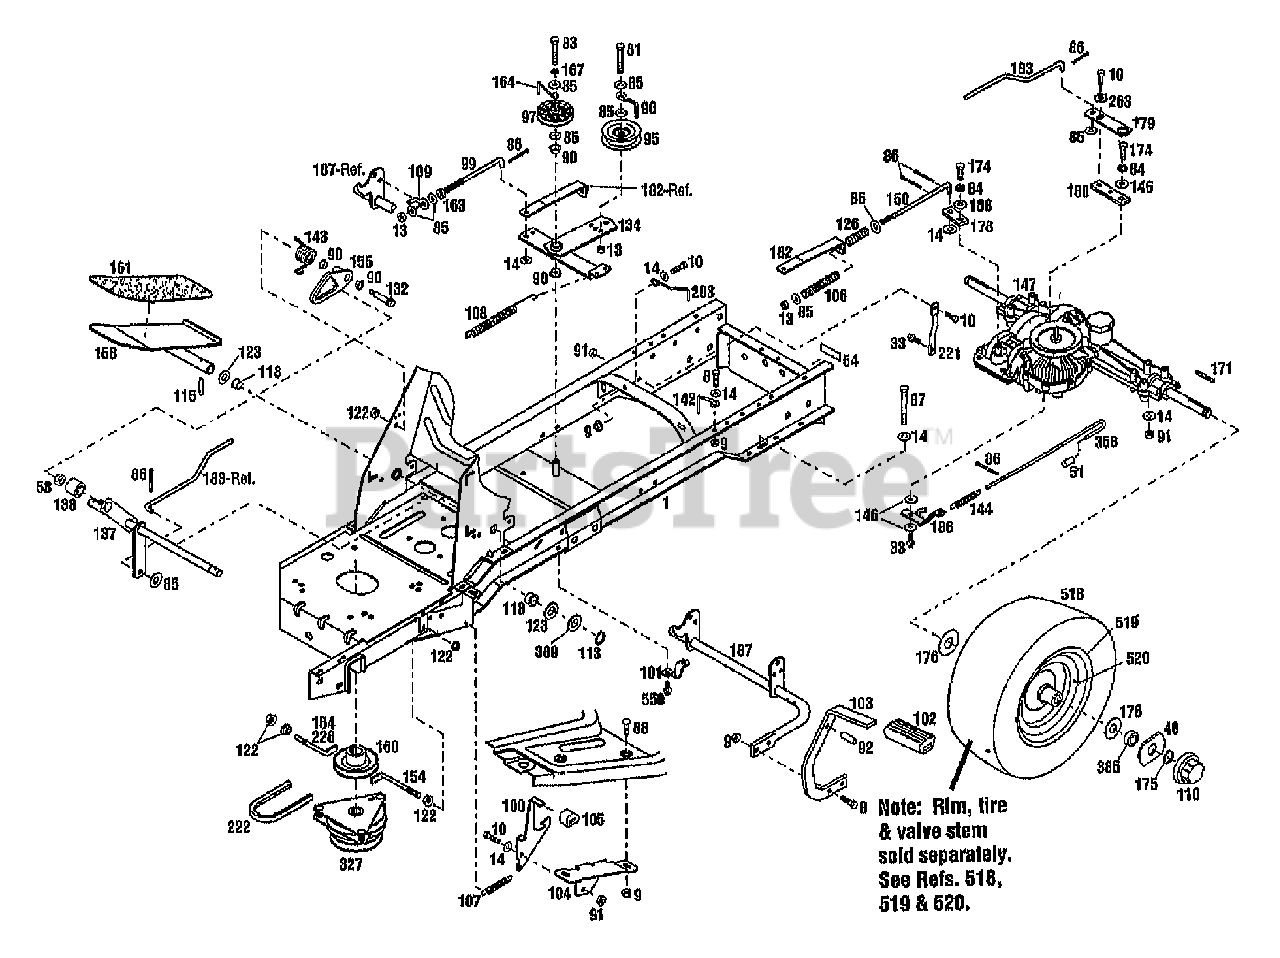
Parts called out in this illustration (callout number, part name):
1	ASSM-FRAME LTX
8	SCR-HH 5/16-18X1.0 G5 ZP
9	NUT-HFLK 5/16-18 ZP
10	SCR-HHC 5/16-18X.75 GR 5 ZP
13	NUT-LOCK 3/8-16
14	WASHER-FLAT 5/16 SAE
33	SCR-HFLK 5/16-18X.75
40	WASHER-SPEC .75X2.50
51	GRIP-HANDLE
54	DECAL-TRANS RELEASE
58	NUT-HT LK 1/4-20
81	SCR-HH 3/8-16X2.0 G5 ZP
83	SCR-HH 3/8-16X1.75 G5 ZP
84	WASHER-LK .25 ZP
85	WASHER-FLAT 3/8 SAE
86	PIN-COTTER .09X.75 ZP
87	SCR-HH 5/16-18X2.75 G5 ZP
88	SCR-CARR 5/16-18X.62 G2 ZP
90	BUSHING-.5X.5 NYLON FLNG
91	NUT-TOP/LK 5/16-18 ZP
92	PIN-DRIVE .312X.75
96	GUIDE-BELT
97	PULLEY-IDLER
99	ROD-CLUTCH
100	LATCH-BRAKE CLUTCH USE1771514
101	CLIP-CLAMP .75 ID
102	PAD-FOOT PEDAL
103	PEDAL-BRAKE
104	BRKT-BRAKE LOCK
105	PAD-BRAKE
106	SPRING-COMPRESSION
107	SPRING-EXTENSION
108	SPRING-EXTENSION
109	ROD-PIVOT
110	CAP-HUB
113	RING-RETAIN .625 ID
115	PIN-ROLL .188X1.0
118	BEARING-FLANGE
122	NUT-HFLK 3/8-16 ZP
123	WASHER-1.115X.637X.06
126	SPRING
132	SCR-SHLDR 3/8-16
134	ARM-IDLER
137	SHAFT-HYDRO PIVOT
138	BEARING-BALL
142	GUIDE-BELT
143	SPRING-TORSION
144	SPRING
146	WASHER-FLAT 5/16 SAE
147	TRANSAXLE-HYDRO
150	ROD-BRAKE
154	RETAINER-CLUTCH (13085,13086)
155	ARM-RETURN NEUTRAL HYDRO
158	ASSM-PEDAL HYDRO
160	PULLEY-ENGINE
161	PAD-FOOT PEDAL
163	NUT-HEX 3/8-16 ZP
164	GUIDE-BELT
167	WASHER-LK .375 @ DEPL
171	KEY-3/16X3/16X1 3/4
174	SCR-HHC 1.4-28 X .50
175	RING-RET."E".577 ID
176	WASHER-1.87X.765X.06 SPECIAL
178	BRAKE-ARM
179	ARM-CONTROL
180	ARM-HYDRO
182	BRACKET-BRAKE
183	ROD-HYDRO CTRL
186	BRACKET-DUMP VALVE
187	ASSM-BRAKE PEDAL
188	WASHER-FLAT .25 DIA
203	GUIDE-BELT
221	SUPT-TRANSAXLE
222	BELT-V
226	GUIDE-BELT (13085,13086)
263	WASHER-LK .312 PYRAMIDAL
327	CLUTCH-ELECTRIC
358	ROD-DUMP VALVE
385	SPACER-1.0X.766X.413
389	WASHER-1.0X.64X.029
518	TIRE-20X8.00-10
519	WHEEL-REAR
520	STEM-VALVE
550	SCR-HFLK 5/16-18X.75
600	PAINT-BLACK SPRAY
601	PAINT-RED SPRAYCAN POWDER
